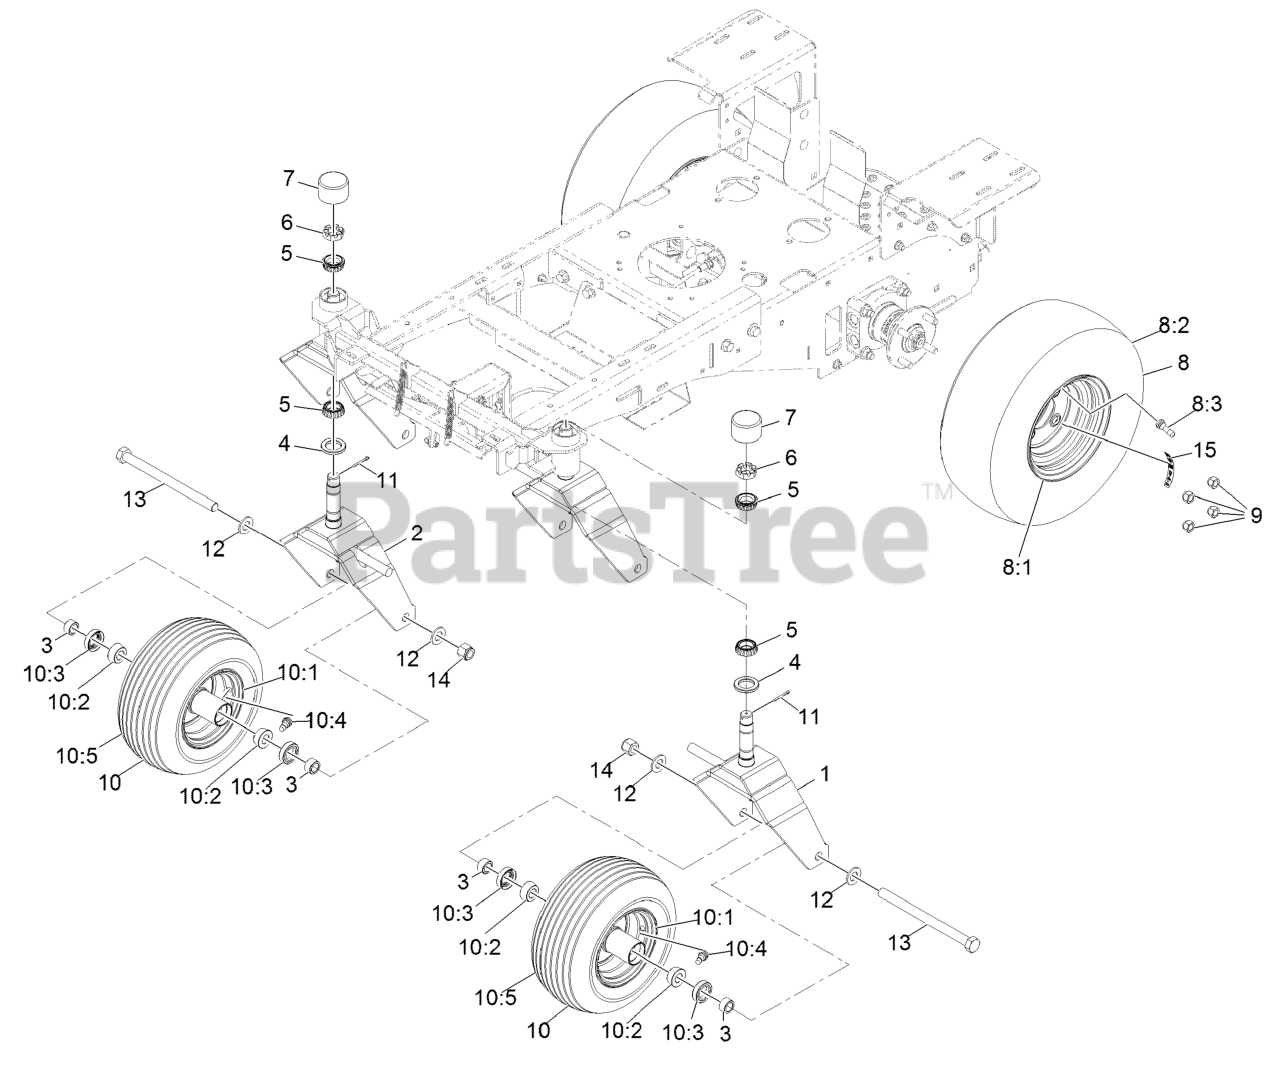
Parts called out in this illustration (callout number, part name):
1	Wld, Caster, L, Jr36, 36R
2	Wld, Caster, R, Jr36, 36R
3	SPACER-AXLE
4	SEAL-GREASE
5	CONE-BEARING, OUTER
6	NUT-SHH
7	CAP-DUST, RUBBER
8	TIRE/RIM ASM, K500-4H-BLK
8:1	RIM-8X5.375, CENTERED
8:3	Stem-Valve
9	NUT-LUG
10	TIRE, FRONT, ZPLUG,J36,36
10:1	RIM-6 X 4.5
10:2	BEARING-CONE, TAPERED ROLLER
10:3	SEAL-CASTER
10:4	VALVE
10:5	TIRE-RIB
11	Pin-Cotter
12	WASHER-FLAT
13	SCREW-HH
14	NUT-LOCK, NI
15	DECAL-TORQUE, WHEEL HUB LUG
